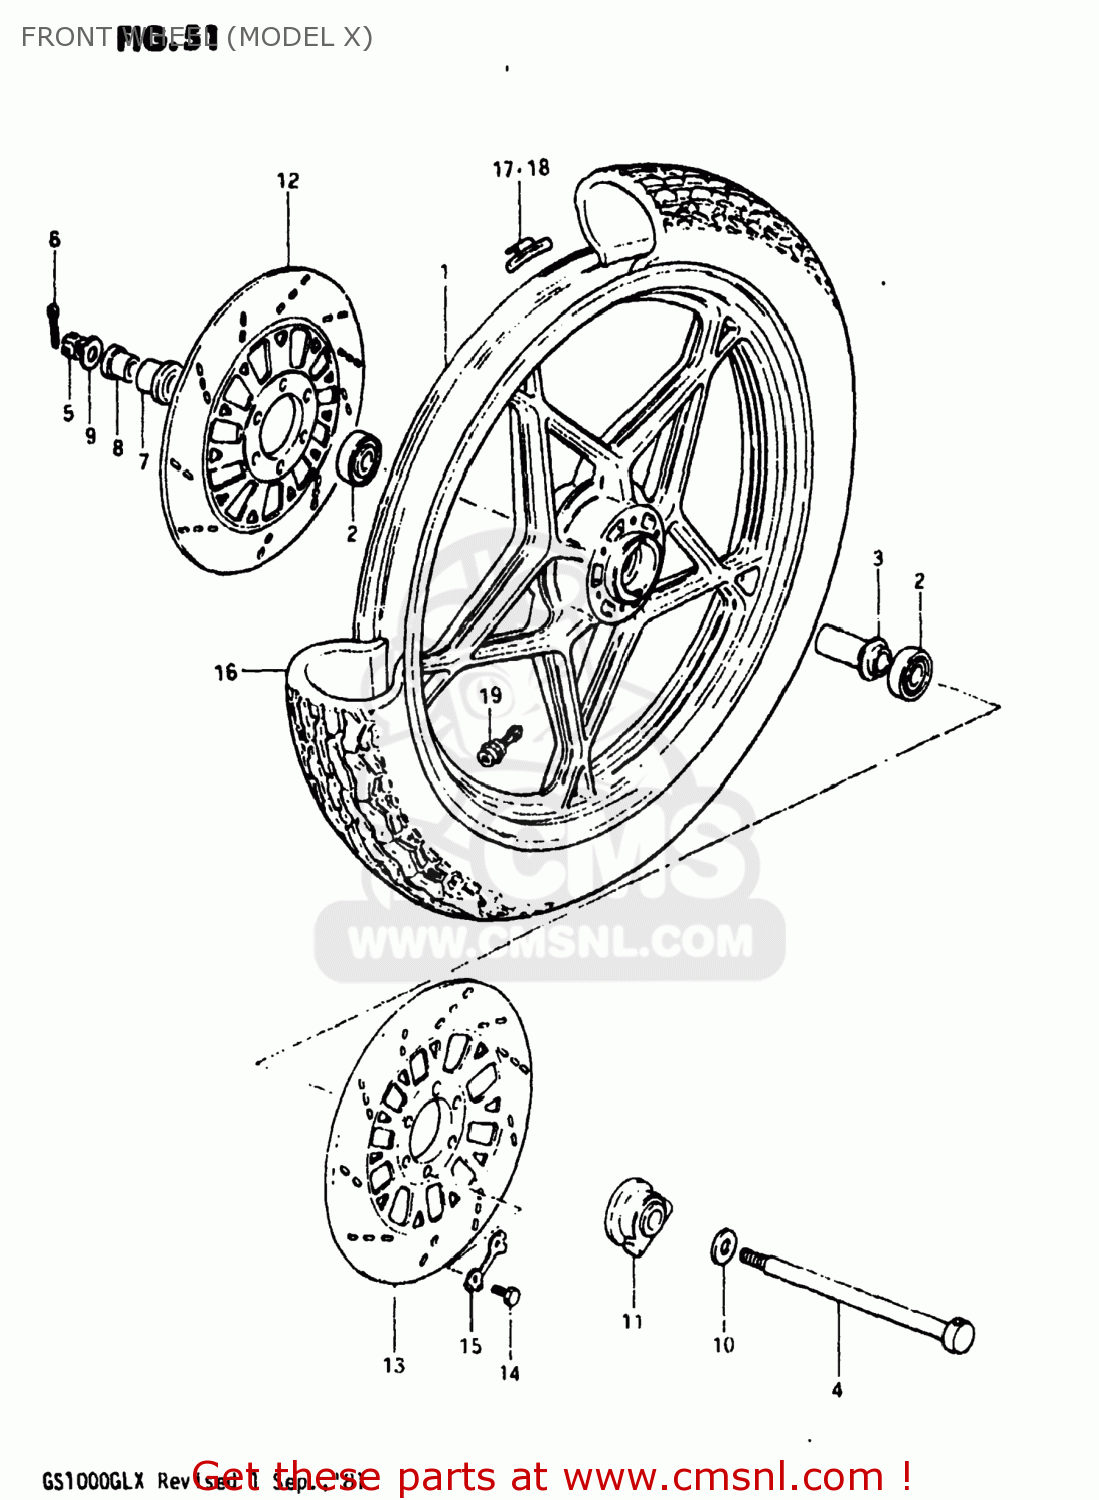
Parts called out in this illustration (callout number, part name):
1	CASTING WHEEL,FRONT 1.85
2	BEARING
3	SPACER,FR HUB BEARING
4	AXLE,FR
5	NUT 12MM
6	COTTER PIN
7	SPACER,FR AXLE,R
8	SPACER
9	WASHER
10	WASHER(15.5X26X2.3)
11	BOX ASSY,SPEEDOMETER GEAR
12	DISC,FR BRAKE,R
13	DISC,FR BRAKE,L
14	BOLT(8X25)
15	WASHER
16	TIRE,FRONT
17	BALANCER,WHEEL
18	BALANCER,WHEEL
19	VALVE ASSEMBLY,WHEEL RIM,J
